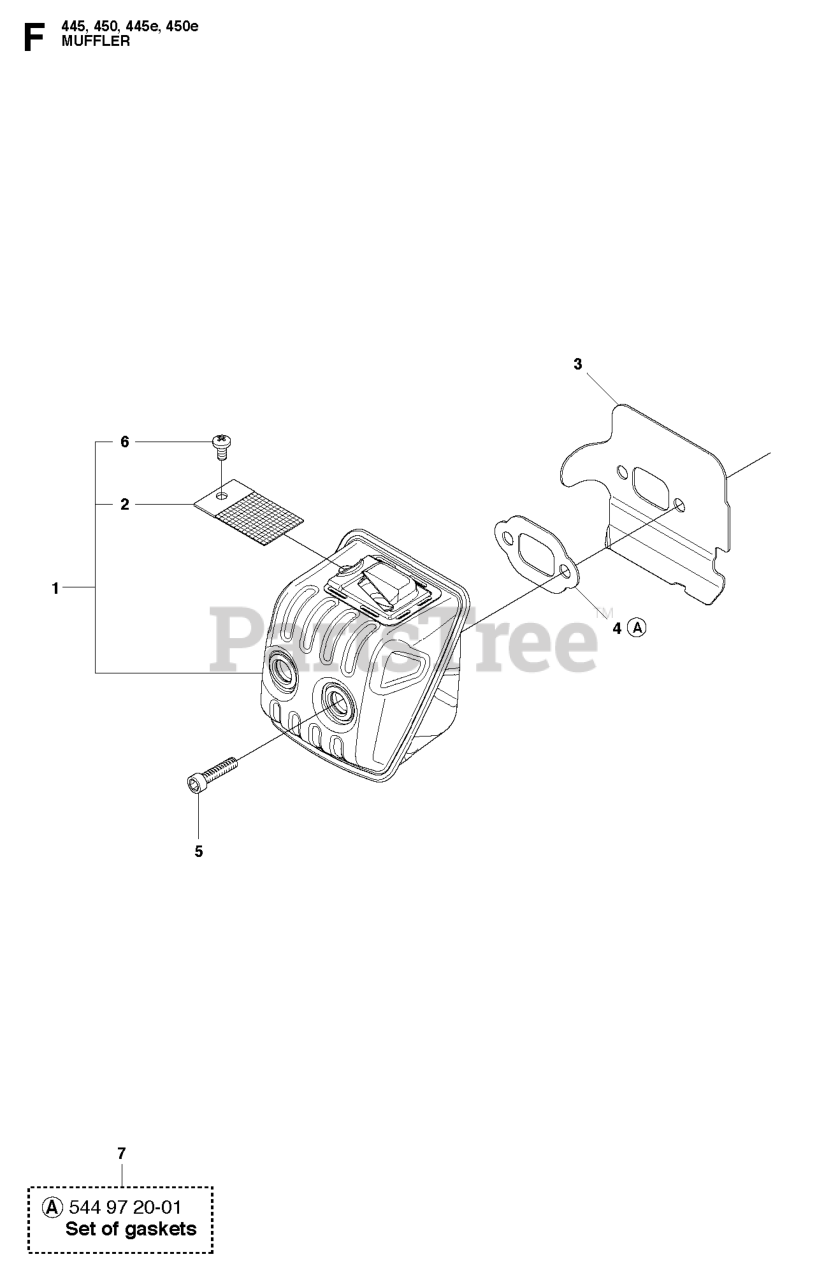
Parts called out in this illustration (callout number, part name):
1	MUFFLER ASSY
2	RP SCREEN
3	HEAT DEFLECTOR
4	RP GASKET
5	SCREW MC6S 6X16
7	GASKET KIT
